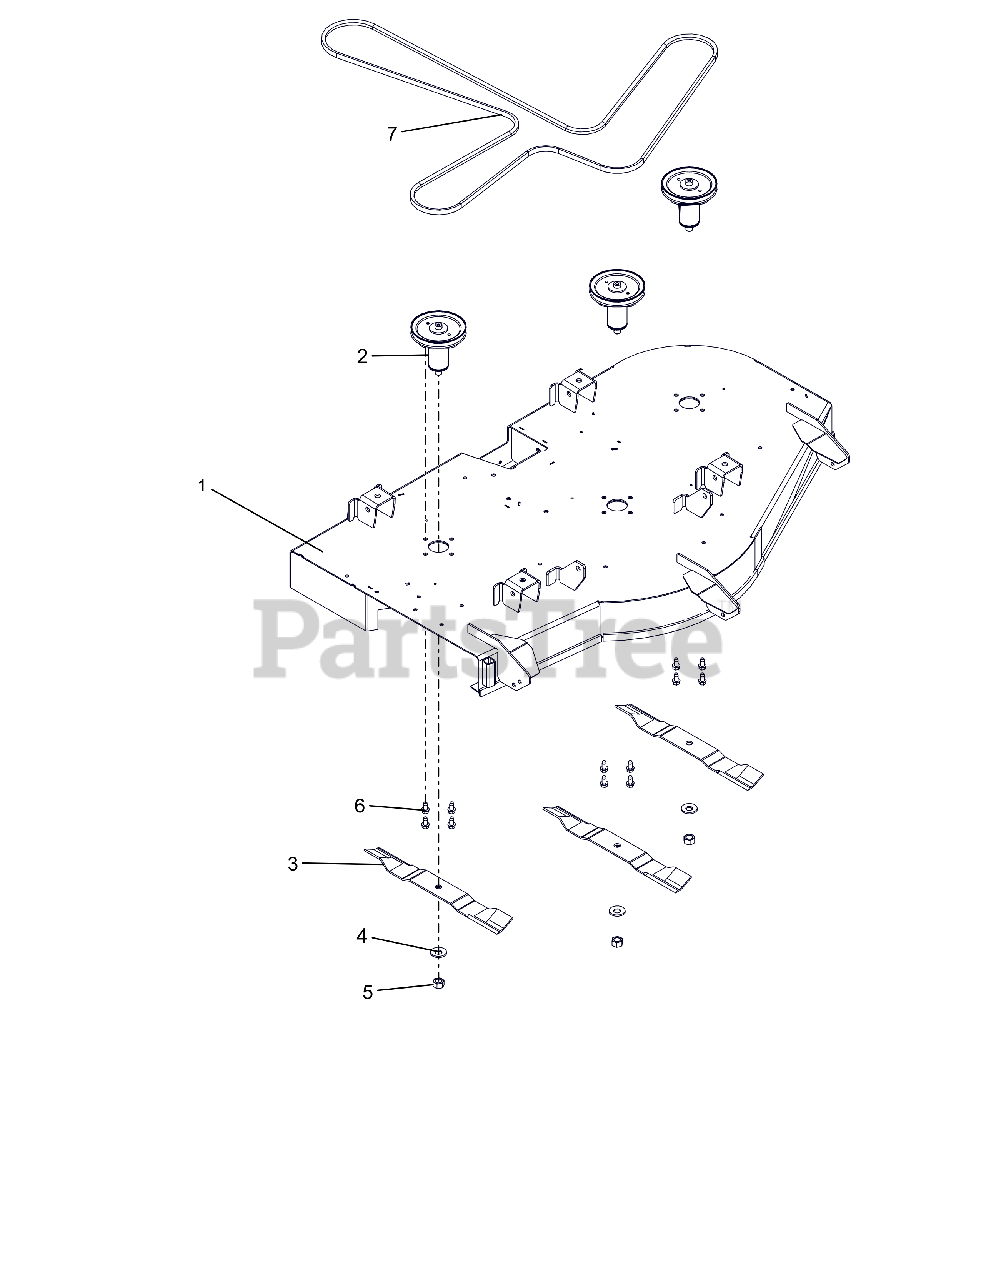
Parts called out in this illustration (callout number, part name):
1	KIT, 52" ARIENS DECK W/DECALS
2	KIT, DECK SPINDLE ASM-52
3	BLADE, 18" - 30 DEG .5 OFFSET
4	WSHR-BLVL .669X1.535X.138
5	NUT-HEX .62-18 YWZC
6	@SCR-TAP .38-16X.75 HWH TR YWZ
7	V-BELT, HA-WRAPPED
